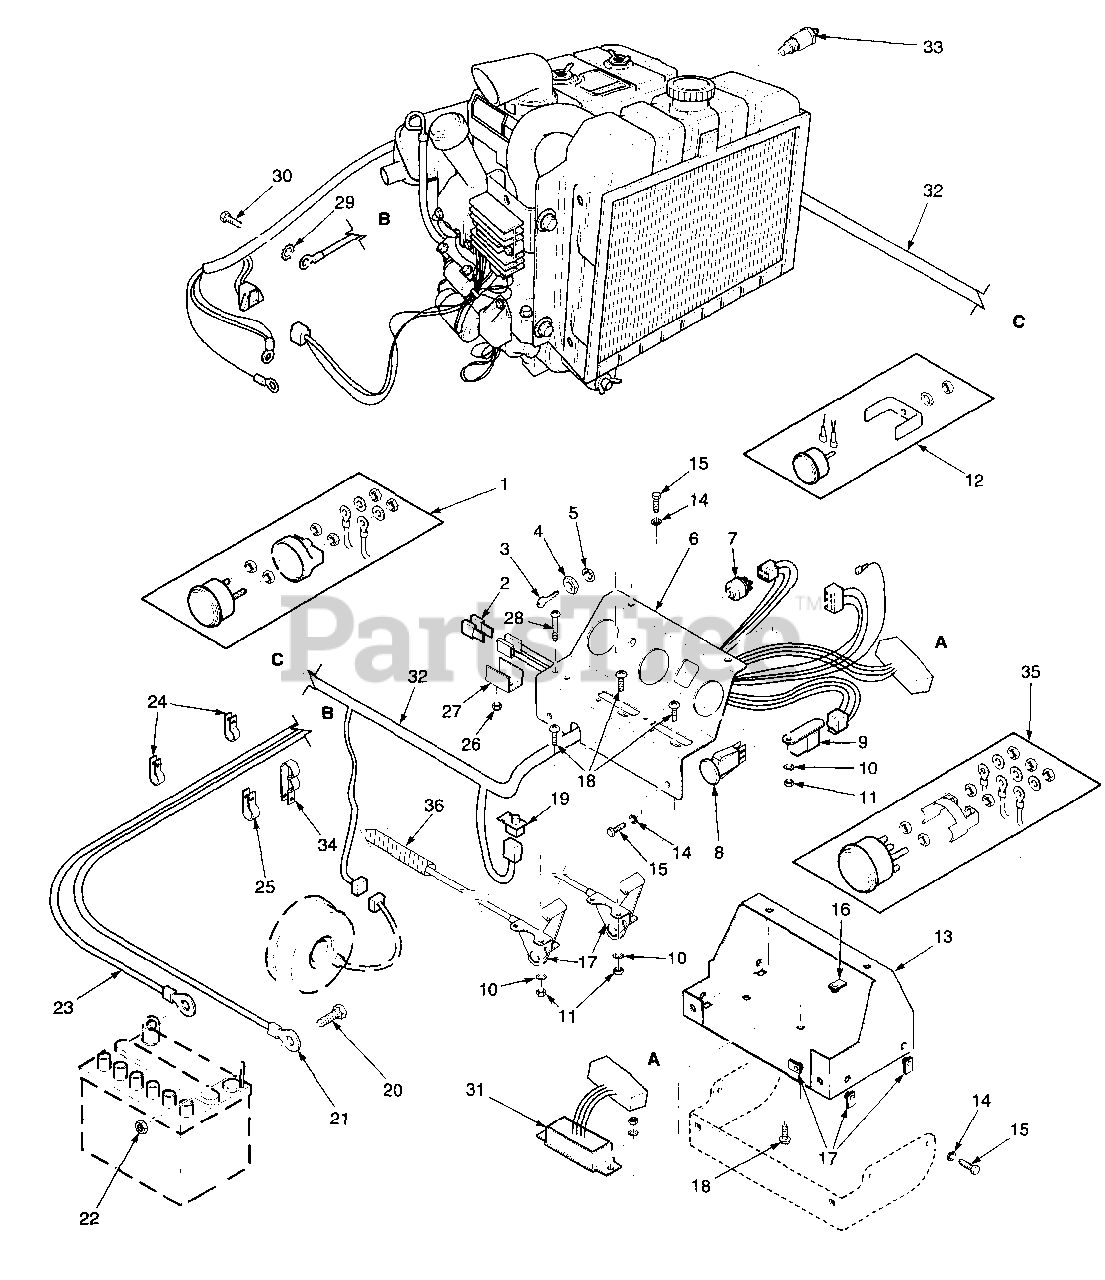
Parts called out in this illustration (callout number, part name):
1	Hour Meter
2	Fuse, 20 AMP
3	Key 8 Ring Assembly
4	Nut, Hex 5/8-32
5	Lockwasher, 5/8" Internal
6	Instrument Panel, Top
7	Key Switch
8	Switch, PTO
9	Relay
10	Lockwasher, #10 External Tooth
11	Nut, Hex #10-32
12	Ammeter
13	Base, Instrument Panel
14	Lockwasher, 1/4"
15	Bolt, Hex Head 1/4-20 x 3/4"
16	U-Nut, 1/4-20
17	Throttle And Choke Controls
18	Screw, Phillips Washer Head #10-32 x 1/2"
19	Switch, Interlock-Seat
20	Bolt, Hex Head 1/4-20 x 1/2"
21	Cable, Battery - Red 36"
22	Nut, Hex 1/4-20
23	Cable, Battery - Black
24	Clamp, Cable 1/2" ID.
25	Clamp, Cable 3/4" ID.
26	Nut, Hex Elastic Stop #10-32
27	Bracket, Fuse Holder
28	Screw, Phillips Washer Head #10-32 x 1-1/2"
29	Lockwasher, 5/16" External Tooth
30	Bolt, Hex Head M8-1.25 x 20
31	Electronic Module
32	Wire Harness, STT-KA
33	Sending Unit, Water Temp.
34	Clamp, Cable
35	Water Temp. Gauge (STT - KA Only)
36	Heatshield, Flexible - 24"
